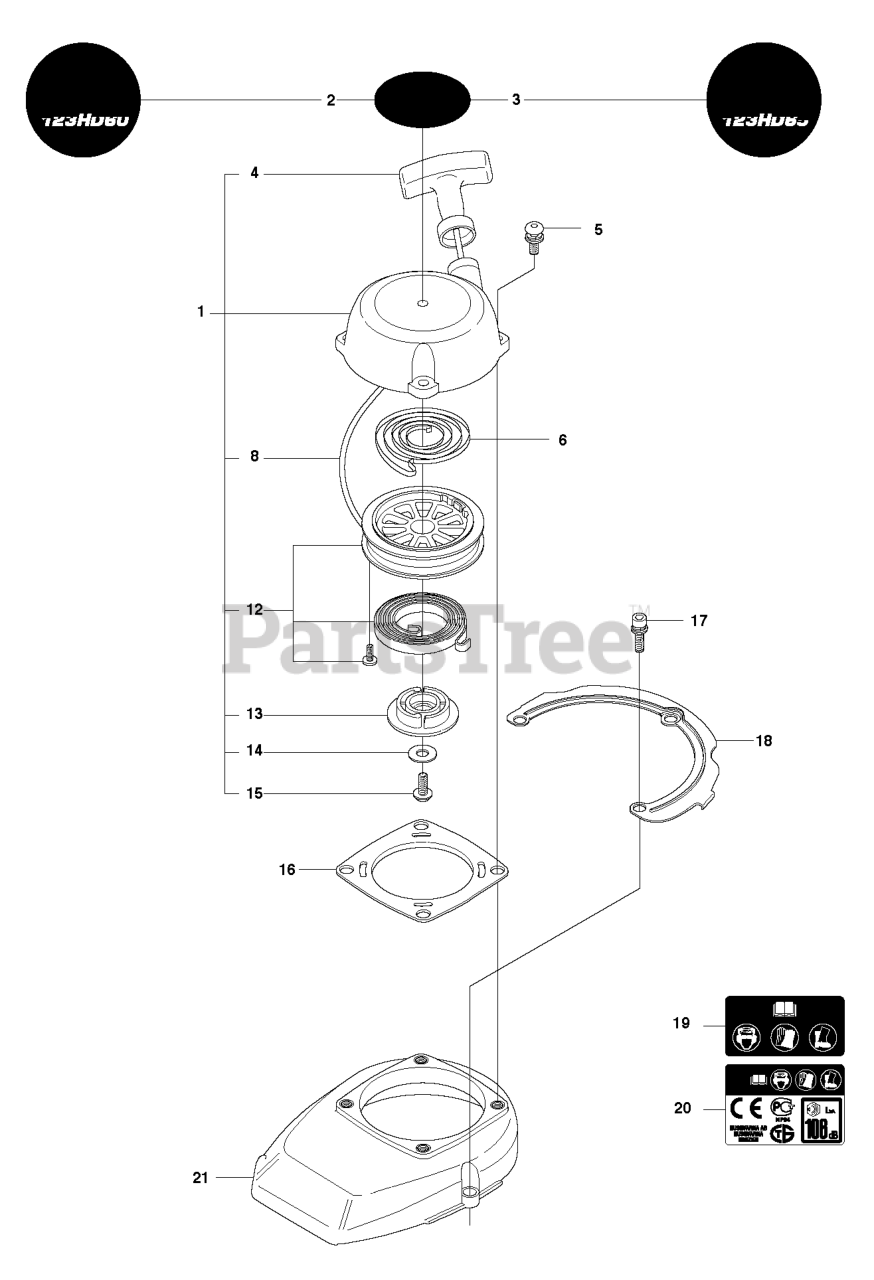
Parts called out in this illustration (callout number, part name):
1	STARTER DEVICE
2	DECAL
3	DECAL STARTER
6	RETURN SPRING
8	STARTER ROPE
12	STARTER PULLEY/SPRING ASSY
13	STARTER PULLEY
19	LABEL
20	LABEL
